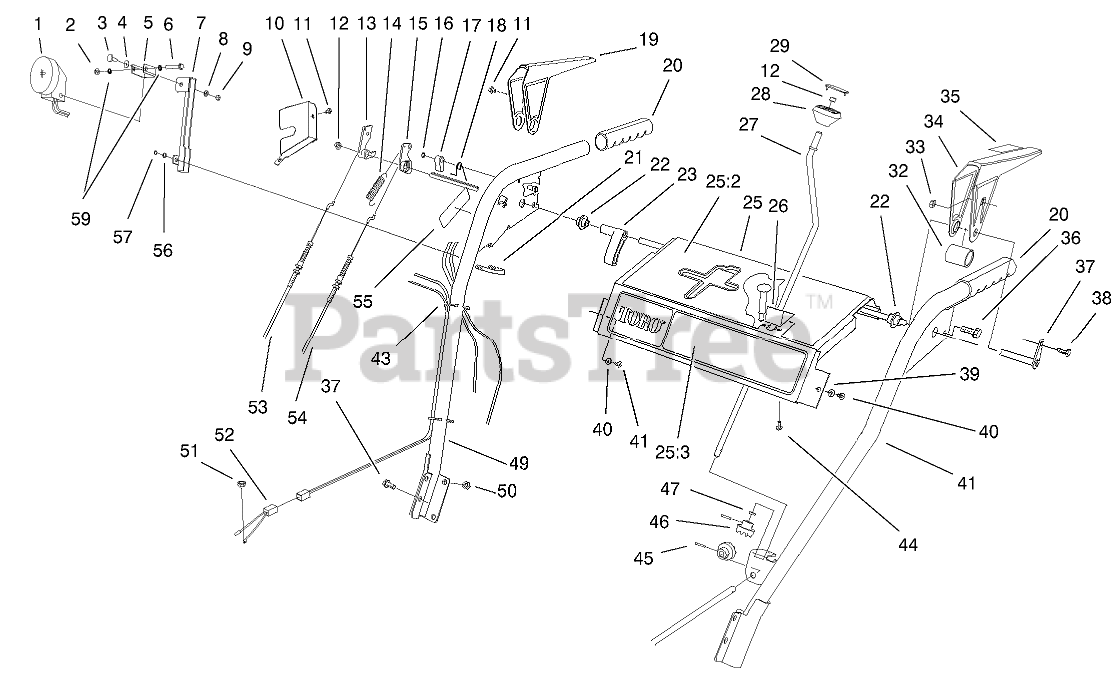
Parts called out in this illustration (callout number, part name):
1	Headlamp ASM (onlyon: 38087)
2	Nut-HF (only on:38087)
3	Screw-CARR (only on:38087)
4	Washer-Flat (onlyon: 38087)
5	Bracket (only on:38087)
6	Screw-HH (only on:38087)
7	Mount-Light (only on:38087)
8	Washer-Lock (onlyon: 38087)
9	Nut-Hex (only on:38087)
10	COVER-LOCK, LEVER
11	SCREW-HH
12	RETAINER-PUSH ON
13	TANG-LOCKING
14	SPRING-EXTENSION
15	CAM-RELEASE
16	E-RING-RETAINER
17	LATCH-LOCKING
18	SPRING-TORSION
19	LEVER-TRACTION, RH
20	GRIP-HANDLE
21	U-Bolt (only on:38087)
22	BUSHING-LEVER
23	LEVER-TRIP
25	Control Panel ASM(only on: 38087)
25	Control Panel ASM(only on: 38592)
25:2	Decal-Control (onlyon: 38087)
25:2	Decal-Top, Panel(only on: 38592)
25:3	Decal-Front Panel(only on: 38087)
25:3	Decal-Panel Front(only on: 38592)
26	PLATE-GUIDE
27	CRANK-ROD, CHUTE
28	KNOB-CONTROL, CHUTE
29	COVER-KNOB
32	SPACER-LEVER, TRACTION
33	NUT-LOCK, NI
34	LEVER-TRACTION, LH
35	Decal-Lever (only on:38592)
36	SCREW-HWHTF
37	CROSS ROD ASM
38	SCREW-HWH
39	WASHER-FLAT
40	SCREW-HWHTF
41	LH HANDLE ASM
43	TIE-CABLE
44	SCREW
45	PIN-SPRING
46	GEAR-UNIVERSAL
47	WASHER-RUBBER
49	Handle ASM (only on:38087)
49	Handle ASM (only on:38592)
49:2	Decal-Warning (onlyon: 38592)
49:2	Decal-Adjustment(only on: 38087)
50	NUT-LOCK, NI
51	Nut-Hex (only on:38087)
52	Wire ASM (only on:38087)
53	CABLE-IMPELLER
54	CABLE-TRACTION
56	Washer-Flat (onlyon: 38087)
57	Nut-Lock (only on:38087)
59	Washer-Lock/Ext(only on: 38087)
